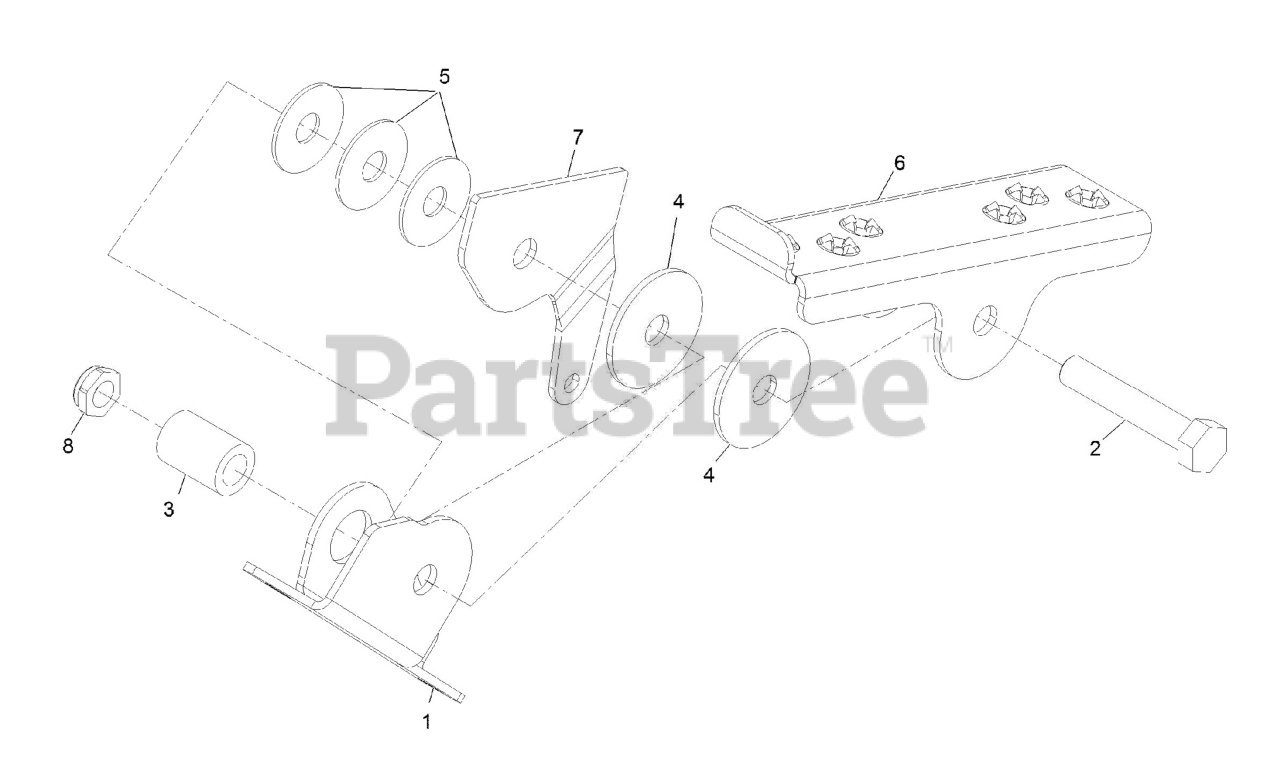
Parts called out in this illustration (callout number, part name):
1	BRACKET-PEDAL MOUNT
2	SCREW-HH
3	SPACER-ROLLER
4	DISC-FRICTION
5	WASHER-DISC, SPRING
6	CHANNEL,PEDAL LINK
7	ARM, FOOT PEDAL
8	NUT-HEX
